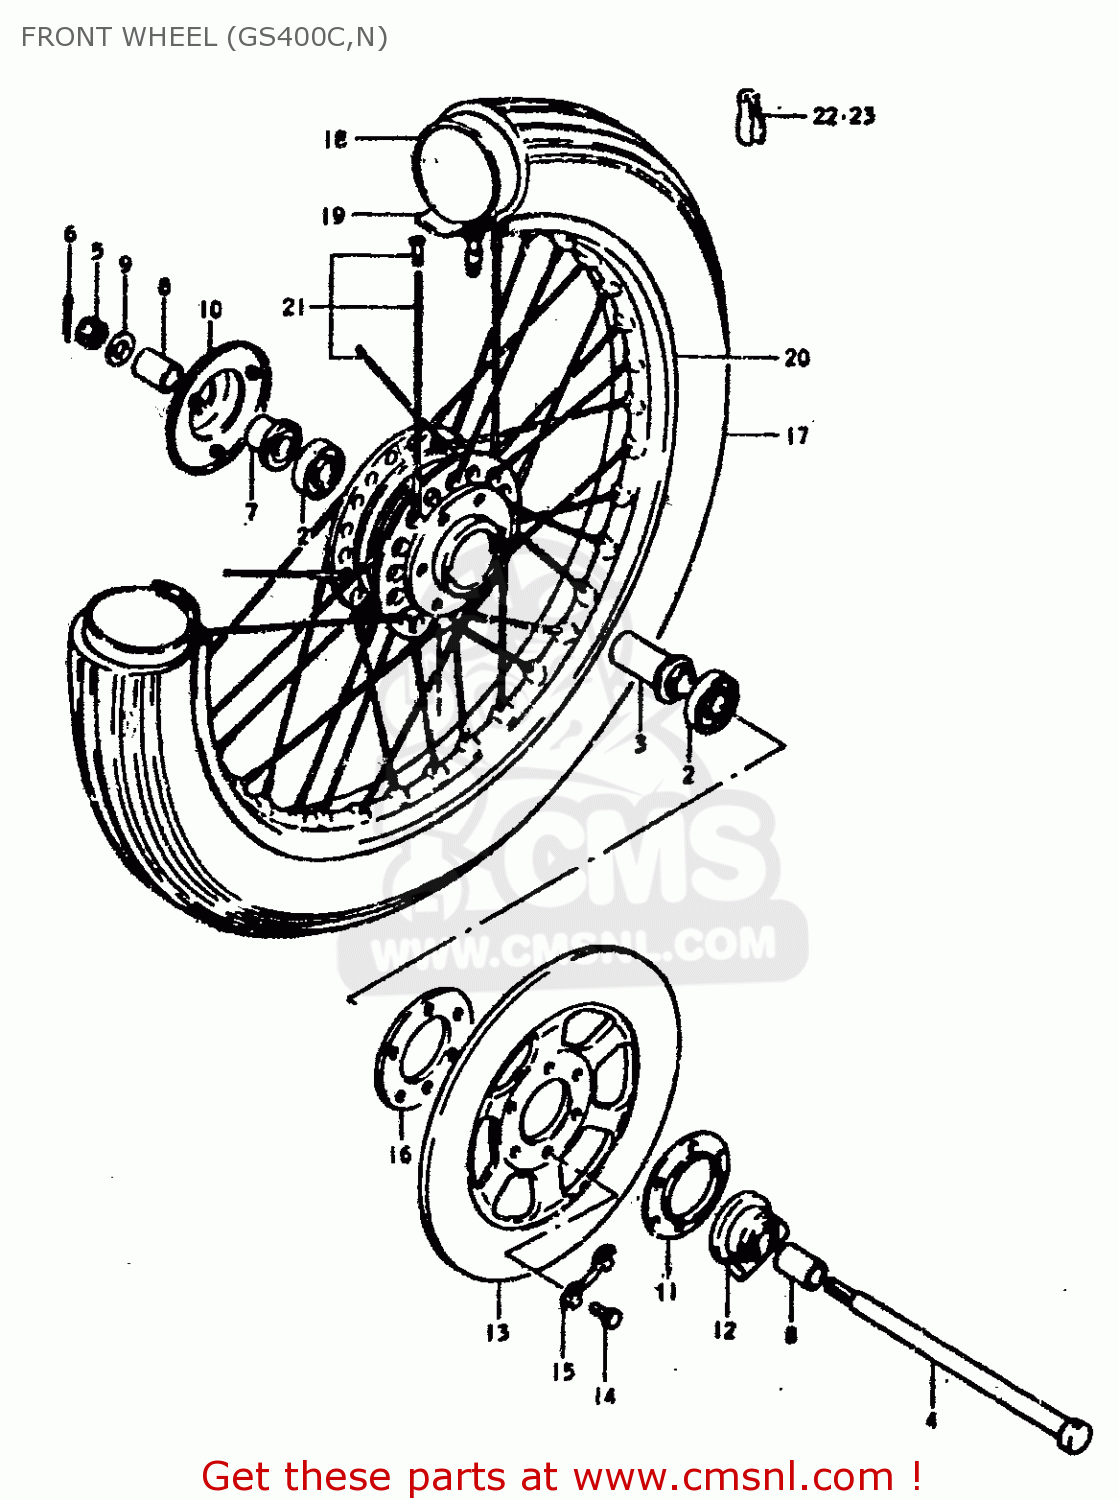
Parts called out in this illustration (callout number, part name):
1	DRUM,FRONT HUB
2	BEARING
3	SPACER,FR HUB BEARING
4	AXLE,FRONT
5	NUT 12MM
6	COTTER PIN
7	SPACER,FR AXLE,R
8	SPACER(15X22X30)
9	WASHER
10	COVER,FR HUB,R
11	DUST SEAL,SPEEDOMETER GEAR BOX
12	BOX ASSY,SPEEDOMETER GEAR
13	DISC,REAR BRAKE
14	BOLT(8X25)
15	WASHER
17	TIRE,FRONT
18	TUBE,INNER
19	PROTECTOR,INNER TUBE
20	RIM,FR WHEEL
21	SPOKE ASSY,FR WHEEL
22	BALANCER,WHEEL (B)
23	BALANCER,WHEEL (30G)
